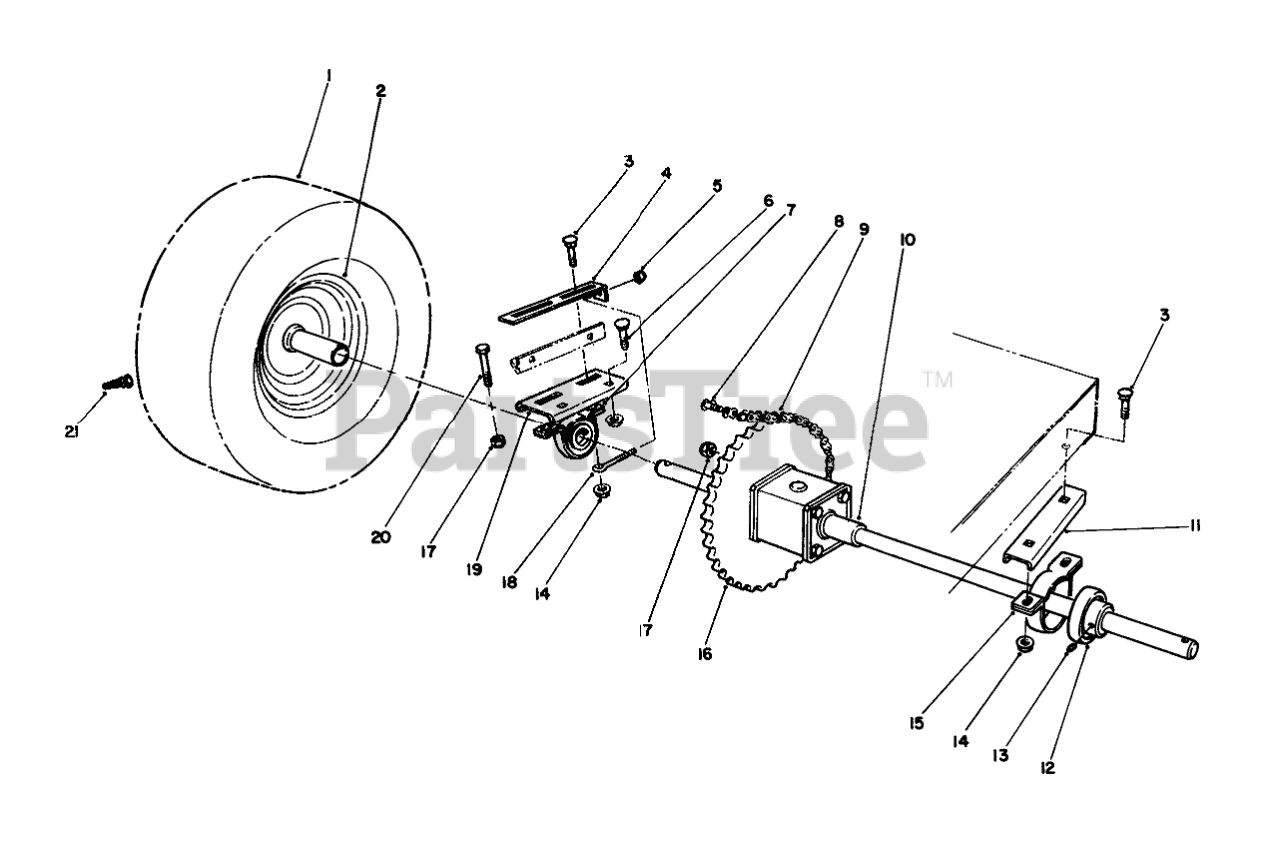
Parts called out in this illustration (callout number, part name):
1	TIRE,PNEU.13X5.00X6
2	WHEEL-REAR
3	BOLT-CARR
4	PLATE-ADJUSTING
5	NUT-LOCK, NI
6	SCREW-CARR
7	RTNR-PILLOW BLK
8	LINK-CHAIN
9	Chain (Incl. Ref. #8)
10	DIFFERENTIAL
11	Support L.H.
12	Bearing (Incl. Ref. #13)
13	SCREW-HSH
14	NUT-HF
16	45 T SPROCKET
17	NUT-LOCK, NI
18	SCREW-ADJUSTING
19	Support R.H.
20	Bolt
21	STEM-VALVE
